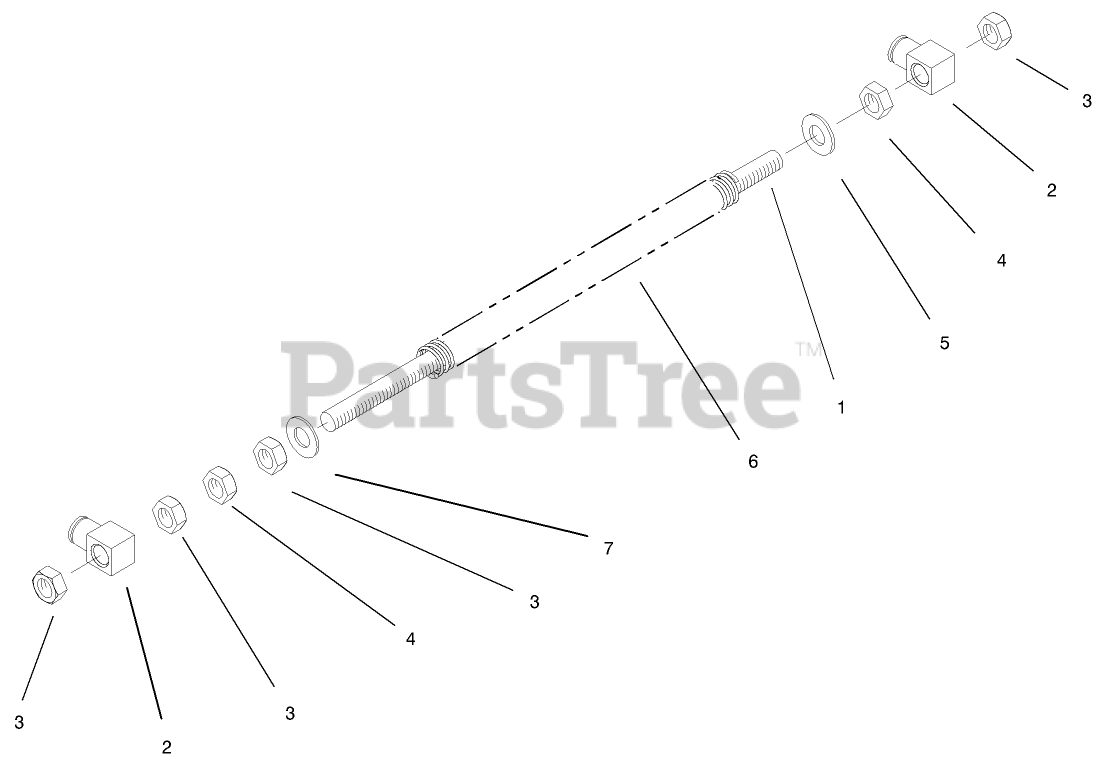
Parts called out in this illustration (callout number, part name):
1	ROD-LIFT, DECK
2	SWIVEL-DECK MOUNT, REAR
3	NUT-HEX
4	NUT-JAM
5	Washer
6	SPRING-COMPRESSION
7	WASHER-FLAT
